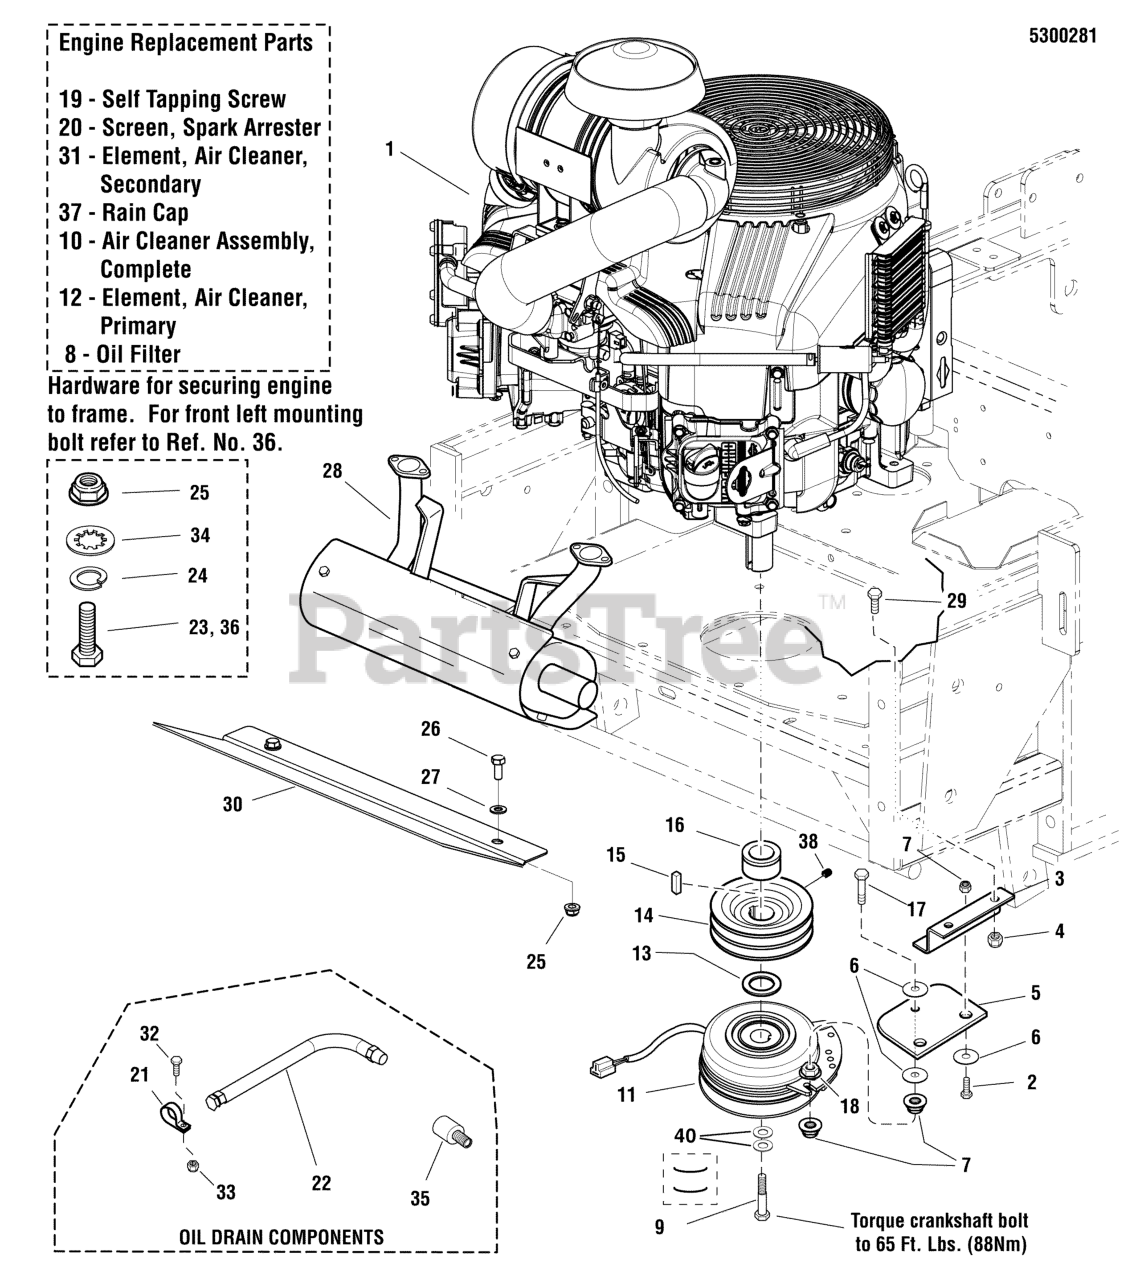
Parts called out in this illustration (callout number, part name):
1	ENGINE, BRIGGS & STRATTON
2	BOLT, 5/16-18 X 3/4 GD5 YZ
3	ANCHOR, CLUTCH - BLK
4	NUT, 3/8-16 HEX NYLOCK FLANGE
5	CLUTCH ANCHOR PAD
6	WASHER, 3/8" FENDER
7	NUT, 5/16-18 HEX NYLOCK FLANGE
8	FILTER, OIL, BRIGGS & STRATTON
9	BOLT, CRANKSHAFT, 7/16" X 2-1/2
10	AIR CLEANER ASSY
11	*CLUTCH, WARNER ELECTRIC, CMS250
12	ELEMENT ASSY
13	SPACER, 1.13 X 2.00 X 0.030, YZ
14	PULLEY, CRANKSHAFT (DOUBLE A)
15	KEY, 1/4 SQ X 1
16	SPACER, 1.13 X 1.75 X 1.09, PM
17	BOLT, 5/16-18 X 2-1/4 TFL, GD5 YZ
18	NUT, 5/16-18 HEX SERRATED FLANGE (SMALL)
19	SELF TAPPING SCREW
20	SCREEN, ARRESTER
21	CLAMP, VINYL
22	HOSE, OIL DRAIN
23	BOLT, 5/16-18 X 1-1/2" GD5
24	WASHER, 5/16 LOCK CZ
25	NUT, 5/16-18 HEX NYLOCK FLANGE
26	BOLT, 5/16-18 X 3/4 GD5
27	WASHER, 5/16" SAE
28	MUFFLER, ASSY, SERVICE PART
29	BOLT, 3/8-16 X 1" GD5 CZ
30	PLATE, HEAT SHIELD, FRAME - BLK
31	ELEMENT, AIR CLEANER, SECONDARY
32	BOLT, 1/4-20 X 1" GD5 CZ
33	NUT, 1/4-20 HEX NYLOCK FLANGE
34	WASHER, 5/16" INT. TOOTH LOCK
35	METRIC ADAPTER, M14-1.5" TO 3/8 NPTF
36	BOLT, 5/16-18 X 2" GD5 YZ
37	CAP, A/C RAIN
38	SET SCREW, 5/16-18 X 3/8, KNURL, W/PATCH
40	BELLEVILLE WASHER 1.1875 X .442 X .089
